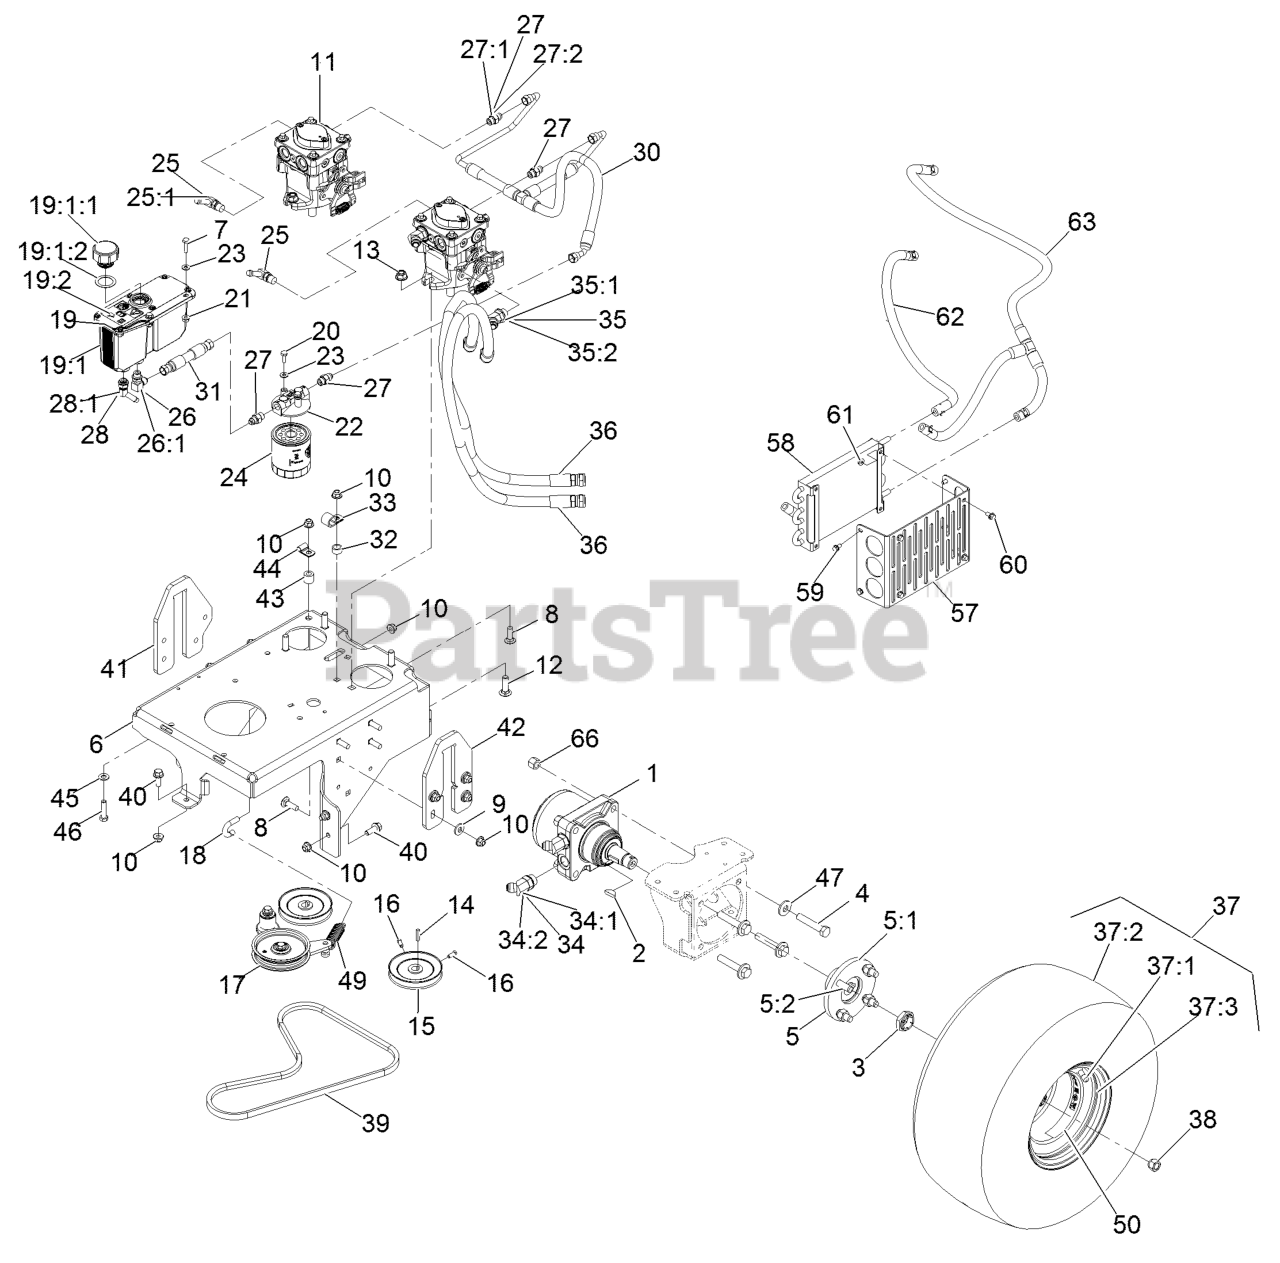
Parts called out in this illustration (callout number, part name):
1	MOTOR-WHEEL
2	KEY-WOODRUFF
3	LOCKNUT
4	SCREW-HH
5	WHEEL HUB / STUD ASM
5:1	HUB-WHEEL
5:2	STUD-TYPE, DRIVE
6	BASE, ENGINE
7	SCREW-HH
8	BOLT-CARR
9	WASHER-BELLEVILLE
10	NUT-HF, NI
11	PUMP - HYDRAULIC
12	SCREW-HH
13	NUT-HF, NI
15	PULLEY-PUMP
16	SCREW-SET
17	PUMP IDLER ASM
18	ANCHOR, SPRING
19	RESERVOIR ASM
19:1	Reservoir-HYD
19:1:1	Cap-Reservoir, HYD
19:1:2	GASKET-CAP
19:2	DECAL-WARNING
20	SCREW-HH
21	NUT-HHF
22	HEAD-FILTER
23	WASHER-FLAT
24	FILTER-25 MICRON, BI-DIRE
25	FITTING-ELBOW, 90
25:1	O-RING
26	FITTING-ELBOW, 90 DEG
27	FITTING-STRAIGHT
28	FITTING-BARBED, 45 DEG
28:1	O-RING
30	HOSE ASSEMBLY - CHARGE
31	HYD HOSE ASM
32	SPACER-SLIDE, SPRING
33	CLIP-LOOM
34	FITTING-HYD, 45 DEG
35	FITTING-HYD, 45 DEG
36	HYD HOSE ASM
37	WHEEL/TIRE ASM
37:1	RIM-8 INCH
37:3	Stem-Valve
38	NUT-LUG
39	BELT-V, LOWER PTO
40	SCREW-HHF 3/8-16 X 1
41	PLATE-LIFT, RH
42	PLATE, LIFT LH
44	CLIP-TUBE
45	WASHER-FLAT
46	SCREW-HH
47	WASHER-SPRING
49	SPRING-EXTENSION
50	DECAL-TORQUE, WHEEL HUB LUG
57	BRACKET, COOLER MOUNTING
59	SCREW-HWH
60	SCREW-HHF
61	NUT-KEPS
62	HOSE-HYDRAULIC
63	HOSE ASM-HYD LP 3/8
66	NUT-LOCK, NI
